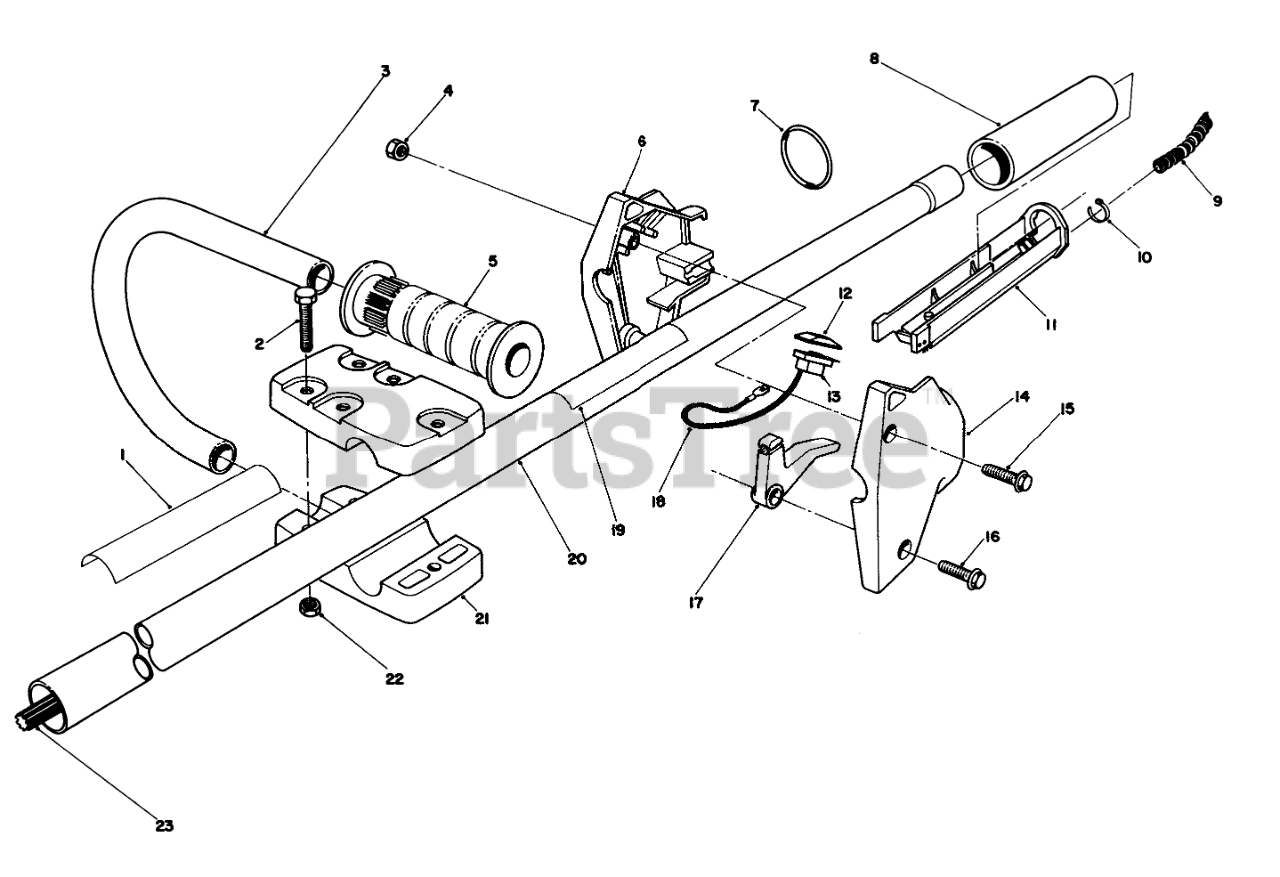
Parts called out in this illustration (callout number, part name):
1	Decal-TC 4000
2	SCREW-HH
3	Tube-Handle
4	NUT-LOCK, NI
5	LH GRIP
6	THROTTLE HSG.R H
7	RING-HARNESS
8	GRIP - RUBBER
9	CABLE COVER
10	TIE-CABLE
11	TROUGH 1"
12	SWITCH COVER-BLACK
13	SWITCH
14	THROTTLE HSG. L H
16	SCREW-HWH
17	THROTTLE LEVER
18	WIRE ASM
19	Decal
20	TUBE ASSEMBLY
21	CLAMP
22	NUT-LOCK, NI
23	SPLINED SHAFT
